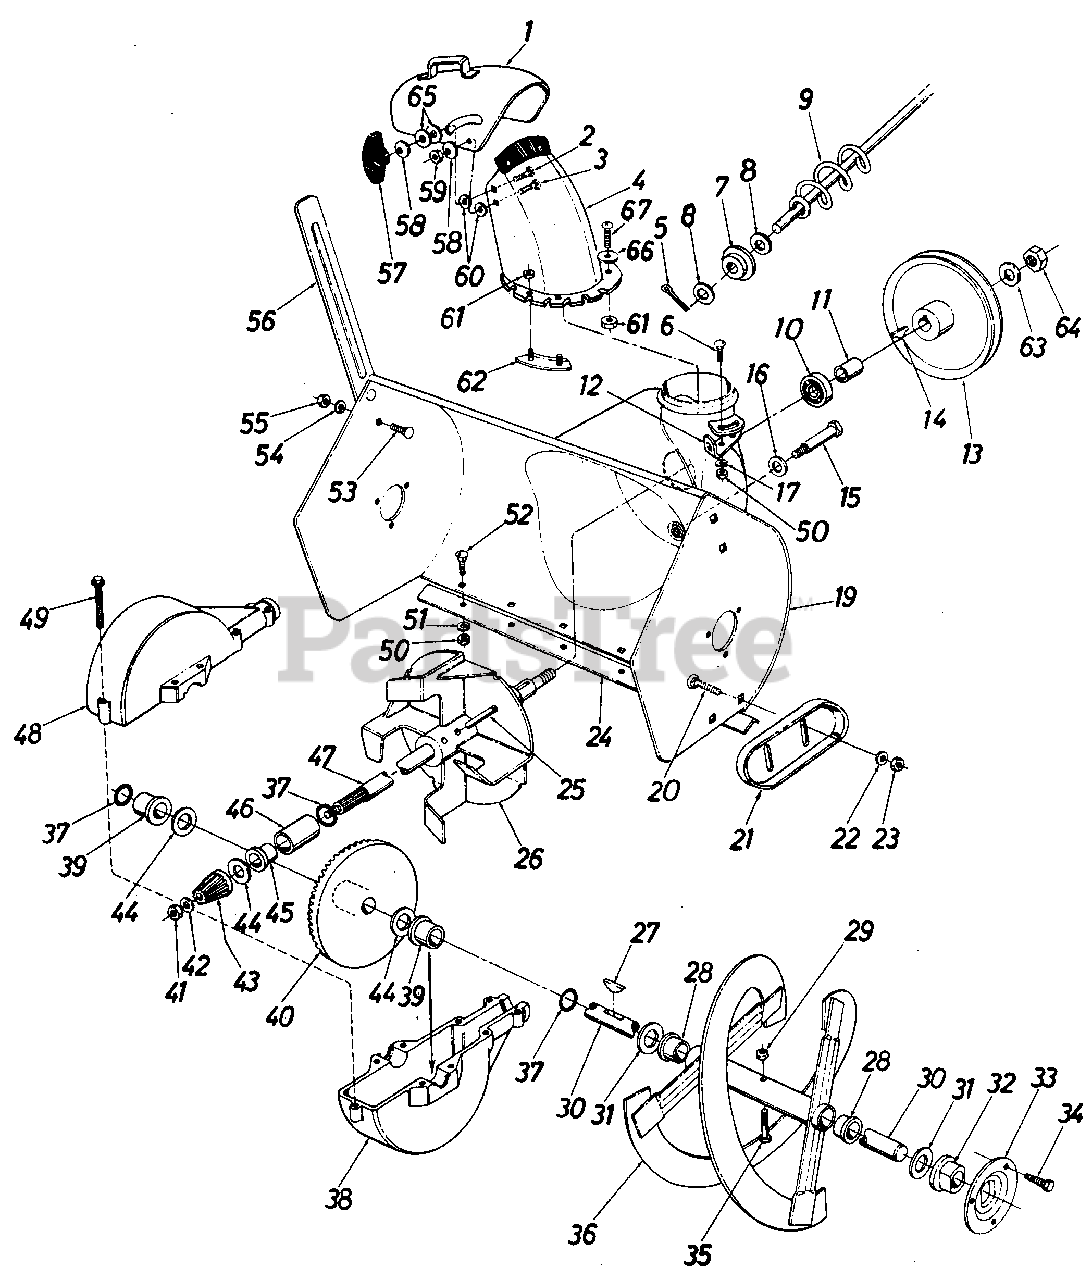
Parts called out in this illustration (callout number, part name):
1	Top Chute Ass'y.
2	Carriage Bolt 5/16-18 x 1.00" Lg.
3	Carriage Bolt 5/16-18 x .62" Lg .
4	Chute Ass'y.
5	Cotter Pin
6	Carriage Bolt 5/16-18 x .75" Lg.*
7	Hex Bushing
8	Fl-Wash. .385 I.D. x .62" O.D.
9	Chute Crank Ass'y.
10	Ball Brg 62" I.D. x 1.38" O.D.
11	Spacer.63" I.D. x .88" O.D. x .900" Lg.
12	Chute Crank Brkt.
13	1/2" "V"-Pulley .625" I.D. x 7.50" O.D.
14	#61 Hi-Pro Key 3/16" x 5/8" Dia.
15	Shld. Bolt .50" Dia. x 2.11" Lg .
16	Bell-Wash. .40" I.D. x .88" O.D. x .06
17	Bell-Wash. .34" I.D. x .88" O.D.
19	24" Blower Housing Ass'y.
20	Carriage Bolt 3/8-16 x .62" Lg.
21	Slide Shoe
22	Bell-Wash. 3/8" I.D.
23	Hex Jam Nut 3/8-16 Thd.
24	24" Shave Plate
25	Spring Pin Spiral 1/4" Dia. x 1.50" Lg.
26	11" Dia. Blower Fan Ass'y.
27	#9 Hi-Pro Key 3/16 x 3/4" Dia.
28	Flange Brg. .75" I.D. x .88" O.D. x .62
29	Hex Ins. L-Nut 5/16-18
30	Spiral Axle
31	Fl-Wash. .75" I.D. x 1.50" O.D. x .06
32	Flange Brg. w/ Flats .755" I.D.
33	Bearing Housing
34	Hex Wash. Hd. Self-Tap Scr. 5/16-24 x .50" Lg.
35	Hex Bolt 5/16-18 x 1.50" Lg.
36	24" Spiral Ass'y.-L.H.
36	24" Spiral Ass'y.-R.H.
37	O-Ring-3/4" I.D.
38	Bevel Gear Housing-Lower Half
39	Plastic Flange Brg. .755" I.D.
40	Bevel Gear
41	Hex Cent. L-Nut 5/16-24 Thd.
42	Fl-Wash. .34" I.D. x .62" O.D. x .06
43	Pinion Gear
44	Fl-Wash. .75" I.D. x 1.25" O.D. x .06
45	Flange Brg. .755" I.D.
46	Sleeve Brg. .755" I.D.
47	Blower Axle
48	Bevel Gear Housing-Upper Half
49	Hex Wash. Hd. Self-Tap Scr. 1/4-20 x 1.00" Lg.
50	Hex Nut 5/16-18 Thd.
51	Bell-Wash. .34" I.D. x .88" O.D.
52	Carriage Bolt 5/16-18 x .62" Lg.*
53	Carriage Bolt 5/16-18 x .62" Lg.*
54	L-Wash. 5/16" I.D.*
55	Hex Nut 5/16-18 Thd.
56	Drift Cutter Bar
58	Bell-Wash . .34 " 1. D. x .88" O.D.
59	Hex Cent. L-Nut 5/16-18 Thd.
60	Fl-Wash. .53" I.D. x 1.25" O.D. x .100
61	Hex Cent. L-Nut 1/4-20 Thd.
62	Chute Flange Keeper Ass'y.
63	Fl-Wash. .64" I.D. x .94" O.D. x .06
64	Hex Jam Nut 5/8-18 Thd.
65	Fl-Wash. .344 I.D. x 1.125 O.D.
66	Fl-Wash.
67	Hex Bolt 1/4-20 x .50"
